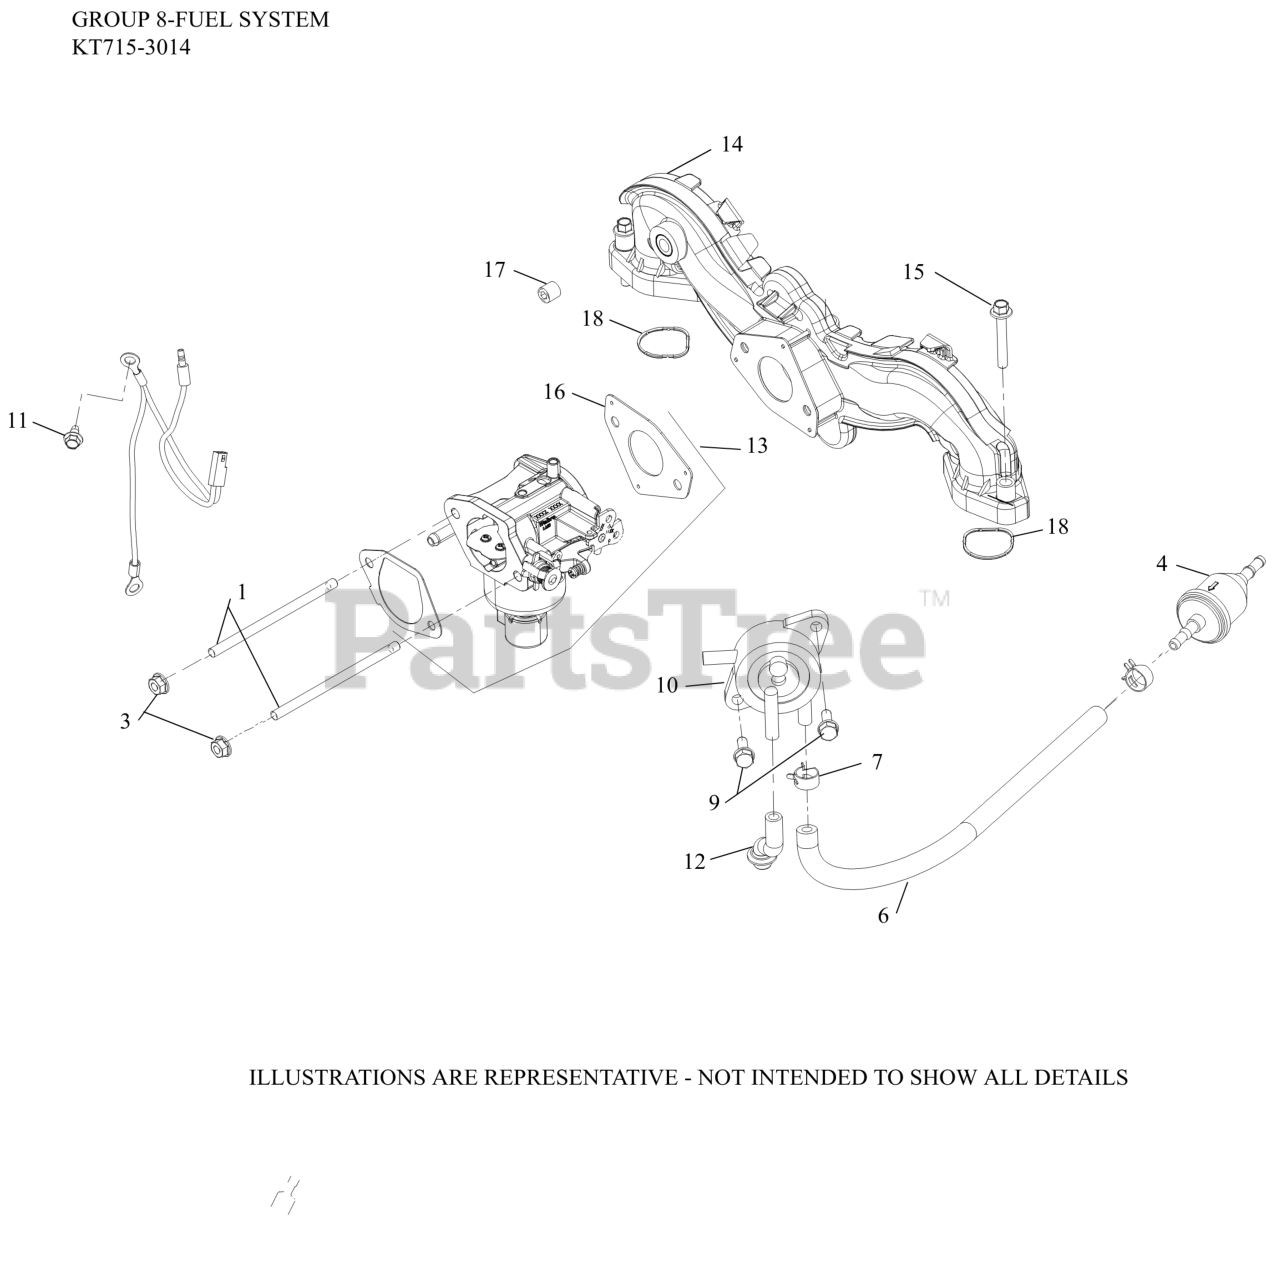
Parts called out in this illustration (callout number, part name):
3	NUT, FLG M6X1.0
4	FILTER,FUEL 51 MICRON (FUEL PUMP)
6	HOSE,LW PERM.FUEL 24.00"-USE 25 111 81-S
7	SPRING CLAMP, HOSE
9	SCREW, TAP M6X1.7X18
10	PUMP, FUEL (PULSE)-(#2539326S)
11	SCREW, THREAD FORMING
12	HOSE, PULSE PUMP(STEEL COVERS)
13	KIT,CARB(WALBRO)
14	KIT, INTAKE MANIFOLD-(#24164277S)
15	SCREW, FLG M6X1.0X40
16	GASKET, CARBURETOR
17	PLUG, CTSK PIPE 1/8"
18	O-RING, INTAKE PORT (PIM)
NI	KIT,REPAIR OVERHAUL(WALBRO)
NI	KIT,BOWL O-RING(WALBRO)
NI	KIT, HI ALTITUDE (5000 FT) 22MM
NI	KIT, SOLENOID REPAIR
NI	KIT, FLOAT REPAIR
NI	CLIP, CABLE (KM)
